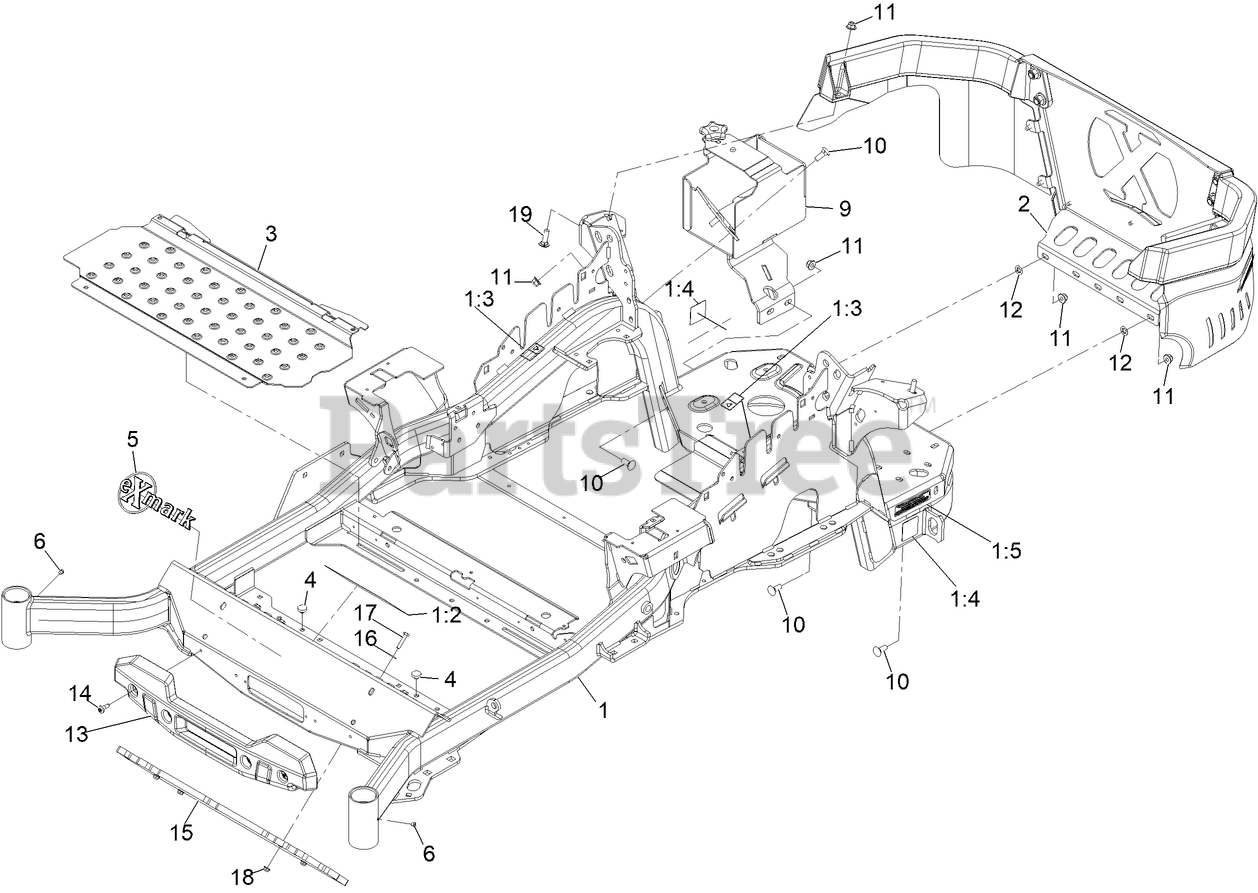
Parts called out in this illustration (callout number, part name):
1	ASM-Mainframe W/Decals
1:2	DECAL-DANGER
1:3	DECAL-WARNING
1:4	DECAL-HAZARD, PINCHED FINGER
1:5	DECAL-ARRESTOR, SPARK
2	Cage-Rear [oil Guard]
5	EMBLEM-EXMARK
9	ASM-Battery Box
10	BOLT-CARR
11	NUT-HF, NI
12	NUT-PUSH
13	BUMPER-FRONT
14	SCREW-SHOULDER
15	Weight-Toe Board
16	WASHER-FLAT
17	SCREW-HH
19	BOLT-CARR
